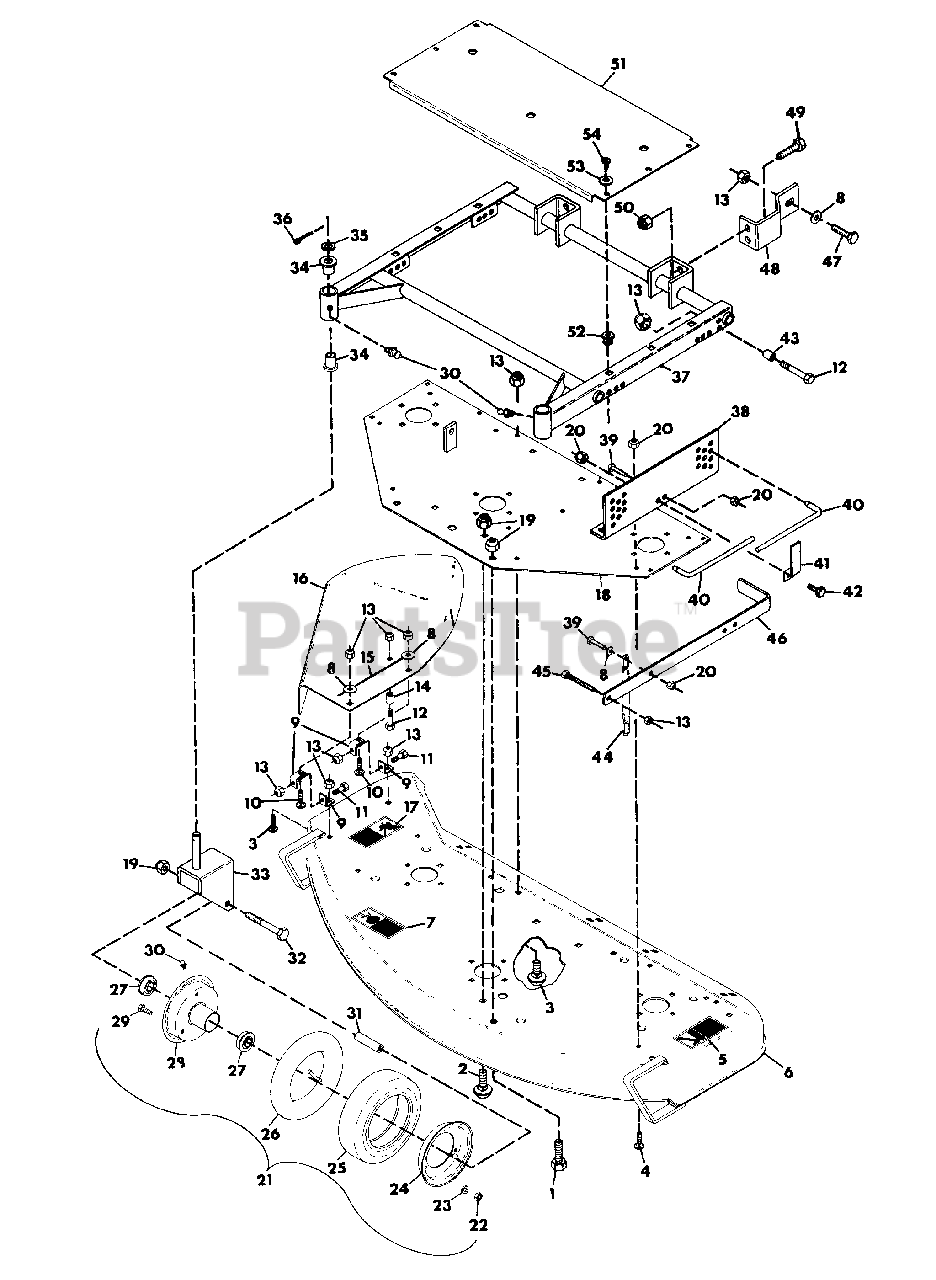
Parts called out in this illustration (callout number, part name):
1	BOLT, HEX 1/2-13X1.25
2	BOLT, 1/2-13X1.00 RD HD SQ NK
3	BOLT, CARRIAGE 3/8-16X.75
4	BOLT, CARRIAGE 5/16-18X1.00
5	DECAL, DANGER FOOT
6	WELDMENT, 50" DECK
7	DECAL, WARNING EYE
8	WASHER, FLAT .406X.812X.065
9	TAB, SPRING
10	BOLT, 3/8-16X1.00 RD HD SQ NK
11	BOLT, HEX 3/8-16X.875
12	BOLT, HEX 3/8-16X1.50
13	NUT, LOCK 3/8-16
14	STOP, CHUTE
15	STRIPE
16	SHIELD, SAFETY EXT. 50" MOWER
17	DECAL, DANGER HAND
18	WELDMENT, SUPPORT PLATE
19	NUT, LOCK 1/2-13
20	NUT, LOCK 5/16-18
21	WHEEL, GAUGE
22	NUT, HEX 3/8-24
23	WASHER, LOCK 3/8 SP HEAVY
24	WHEEL, HALF PLAIN
25	TIRE, GAUGE WHEEL
26	TUBE, INNER
27	BEARING, GAUGE WHEEL
28	WHEEL, HALF WITH TUBE
29	BOLT, HEX 3/8-24X.75
30	FITTING, LUBE 1/4-28
31	BUSHING, WHEEL
32	BOLT, HEX 1/2-13X5
33	WELDMENT, CASTER FORK
34	BUSHING, PIVOT
35	RACE, BEARING THRUST
36	PIN, COTTER .187X1.50
37	WELDMENT, FRAME SUPPORT
38	BRACKET, MOWER SUPPORT L.H.
38	BRACKET, MOWER SUPPORT R.H.
39	BOLT, HEX 5/16-18X1.00
40	PIN, MOWER LOCKING
41	TAB, PIN LOCKING
42	BOLT, HEX 5/16-18X.75
43	BUSHING .391X.622X.670
44	CHAIN, HEIGHT ADJUSTMENT
45	BOLT, HEX 3/8-16X2.00
46	BAR, LIFT
47	BOLT, HEX 3/8-16X1.25
48	BRACE, PRO L.H.
48	BRACE, PRO R.H.
49	BOLT, HEX 1/2-13X1.50
50	NUT, LOCK 1/2-13
51	GUARD, 50" MOWER BELT
52	GROMMET, PLASTIC
53	WASHER, FLAT .281X.625X.065
54	SCREW, 1/4-20X.625
NS	DECAL, GRAVELY LOGO
NS	DECAL, AMERICA
NS	DECAL, PRO-50
